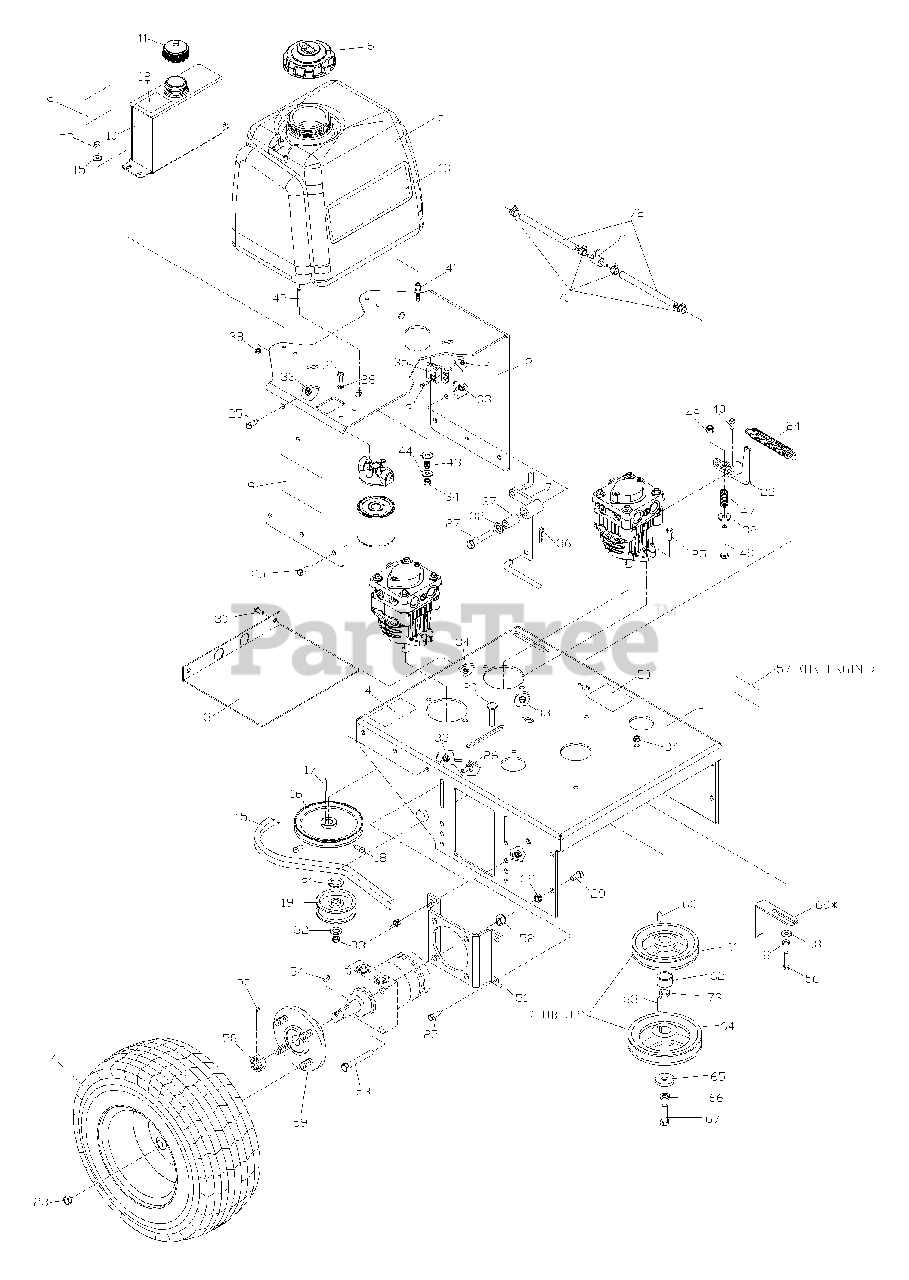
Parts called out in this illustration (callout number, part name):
1	REAR DECK W/DECALS
2	TANK SUPPORT
3	BELT SHIELD
4	WHEEL ASM.
4	RIM
4	VALVE STEM
6	FUEL CAP
7	BELL CRANK
8	WASHER 5/16 LOCK
9	DECAL, CROWN
12	DECAL, MOBIL 1
13	DECAL, WH4817
14	DECAL, BELT DRIVE
17	KEY, METRIC
18	SCREW 5/16 X 625
19	IDLER PULLEY
20	RHSNB 3/8 X 2.0
21	WASHER 1/2 FLAT
22	PUMP ARM WLDMT.
25	HCS 3/8 X 1.0
26	RHSNB 3/8 X 1.0
27	HCS 3/8 X 2.0
28	WASHER 1/4 LOCK
29	HCS 7/16 X 1.0
30	HCS 5/16 X 750
31	HCS 1/4 X 625
32	WASHER 3/8 FLAT
33	NUT 3/8 CTR. LOCK
34	NUT 5/16 CTR. LOCK
36	#2 HAIRPIN
37	SLEEVE BUSHING
38	NUT 1/4 CTR. LOCK
39	NUT 7/16 CTR. LOCK
40	SCREW 5/16 X 625 CONE
44	WASHER 5/16 FLAT
45	WASHER 1/4 FLAT
46	HCS 1/4 X 750
48	HCS 3/8 X 2.750
49	NUT 3/8 NYLOC
50	DECAL, PROP 65
51	MOTOR MOUNT
52	NUT 1/2 NYLOC
53	HCS 1/2 X 2.750
54	KEY #808 WOODRUFF
55	COTTER PIN
56	HCS 5/16 X 1.750
57	DECAL, DANGER
58	NUT SLTD. HEX
60	KEY 1/4 X 750
63	KEY 1/4 X 1.125
65	HEAVY WASHER
66	WASHER 7/16 LOCK
67	HCS 7/16 X 1.500
68	WASHER 5/16 FLAT
69	BELT GUIDE
70	HOSE CLAMP
71	FUEL VALVE
73	MACH. BUSHING
